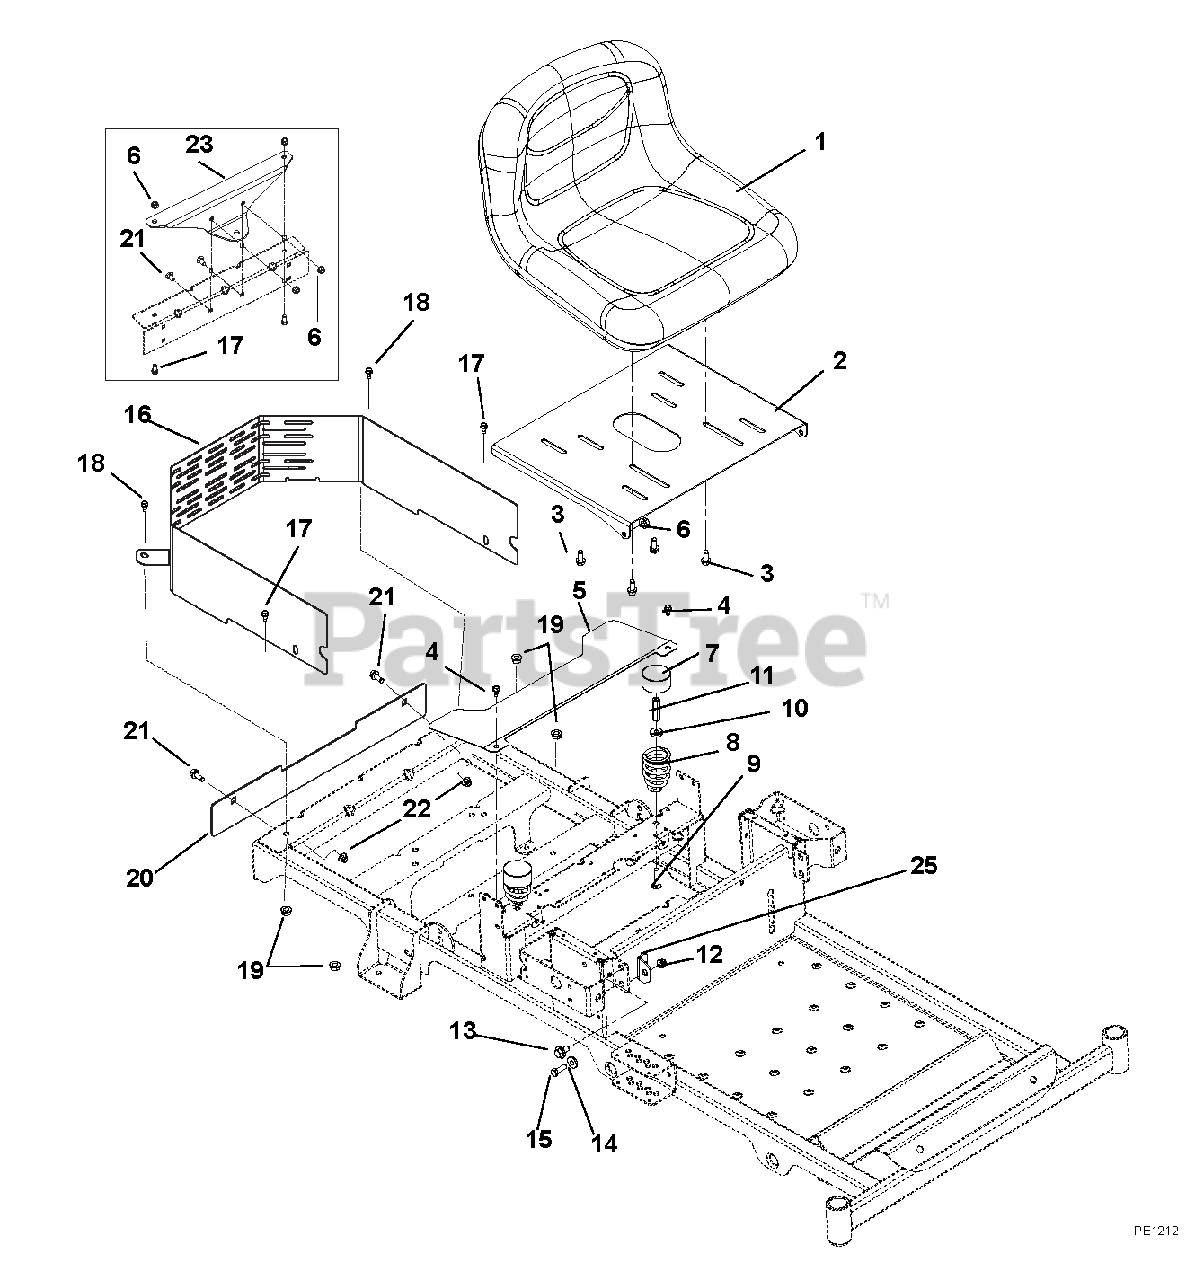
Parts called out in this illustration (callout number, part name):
1	SEAT-13" GREY
2	PLATE, SEAT
3	5/16-18X3/4 HX/W/HD WHIZ
4	@SCR-TAP .25-20X.50 HWH TR YWZ
5	COVER, ZOOM CE FAN
6	@NUT-LK-TOP-FLG .38-16 YWZC
7	HUB CAP
8	SPRING, SEAT
9	@BLT-RDHDSQNK .31-18X1.50 G5YZ
10	WSHR-FL-STL .328X.87X.179 YWZC
11	NUT, COUPLING 5/16-18 X 1 3/4
12	@NUT-LK-NYL-FLG .31-18 YWZC
13	BOLT-SHLDR .375-16X.150
14	BSHG, FLG .325X.499X.26X.88
15	@BLT-HEX .31-18X1.00 GR5 YWZC
16	WALL, CE REACH-IN (ZOOM)
17	@BLT-HEX .38-16X.75 GR5 YWZC
18	@BLT-HEX .38-16X1.00 GR5 YWZC
19	NUT-LK-CTR-FLG .38-16 YWZC
20	FLANGE, ZOOM MUFFLER (CE)
21	@BLT-RDHDSQNK .38-16X.75 G5YZ
22	NUT-LK-CTR-FLG .38-16 YWZC
23	PLATE, BBZ HITCH KIT PLATE
24	@NUT-LK-TOP-FLG .38-16 YWZC
25	BRKT, SEAT STOP
